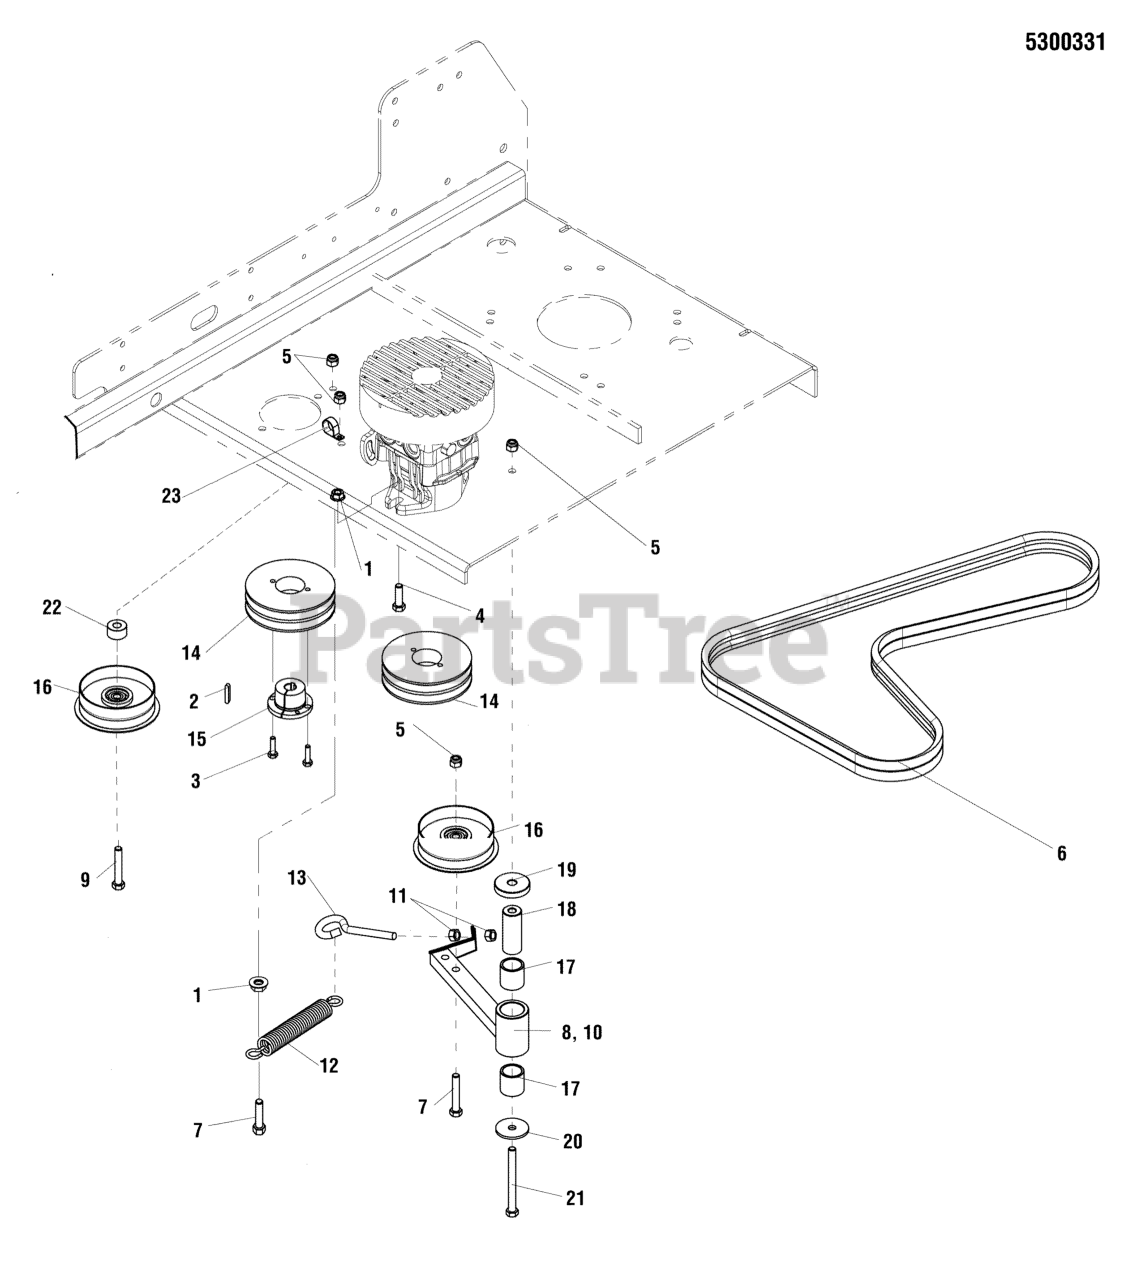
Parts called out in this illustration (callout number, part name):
1	NUT, 3/8-16 HEX SERRATED FLANGE
2	KEY, 5MM SQ. W/ RADIUS
3	BOLT, 1/4-20 X 1" GD5 CZ
4	BOLT, 3/8-16 X 1-1/4" GD5 CZ
5	NUT, 3/8-16 HEX NYLOCK FLANGE
6	BELT, BANDED A-SEC,64.76EL,POLY,RAW EDGE
7	BOLT, 3/8-16 X 2-1/4" GD5 CZ
8	WELD, ARM, PUMP DRIVE IDLER - RED MODEL
9	BOLT, 3/8-16 X 1-3/4" GD5 CZ
10	WELD, ARM, PUMP DRIVE IDLER - ORANGE MODEL
11	NUT, 3/8-16 HEX
12	SPRING, EXTENSION, SWIVEL END
13	EYE BOLT, 3/8-16 X 6", 1" EYE
14	PULLEY, PUMP DRIVE
15	BUSHING, TAPERED HUB
16	PULLEY, IDLER, SINGLE FLANGE
17	BUSHING, BRASS, 1.25X1X1.25
18	SPACER, .39 X 1.00 X 2.55, SS
19	SPACER, .45 X 1.88 X .50
20	SPACER, .39 X 1.00 X 2.55, SS
21	BOLT, 3/8-16 X 4" GD5 CZ
22	SPACER, .39 X 1.00 X .50
23	CLAMP, VINYL INSULATED
